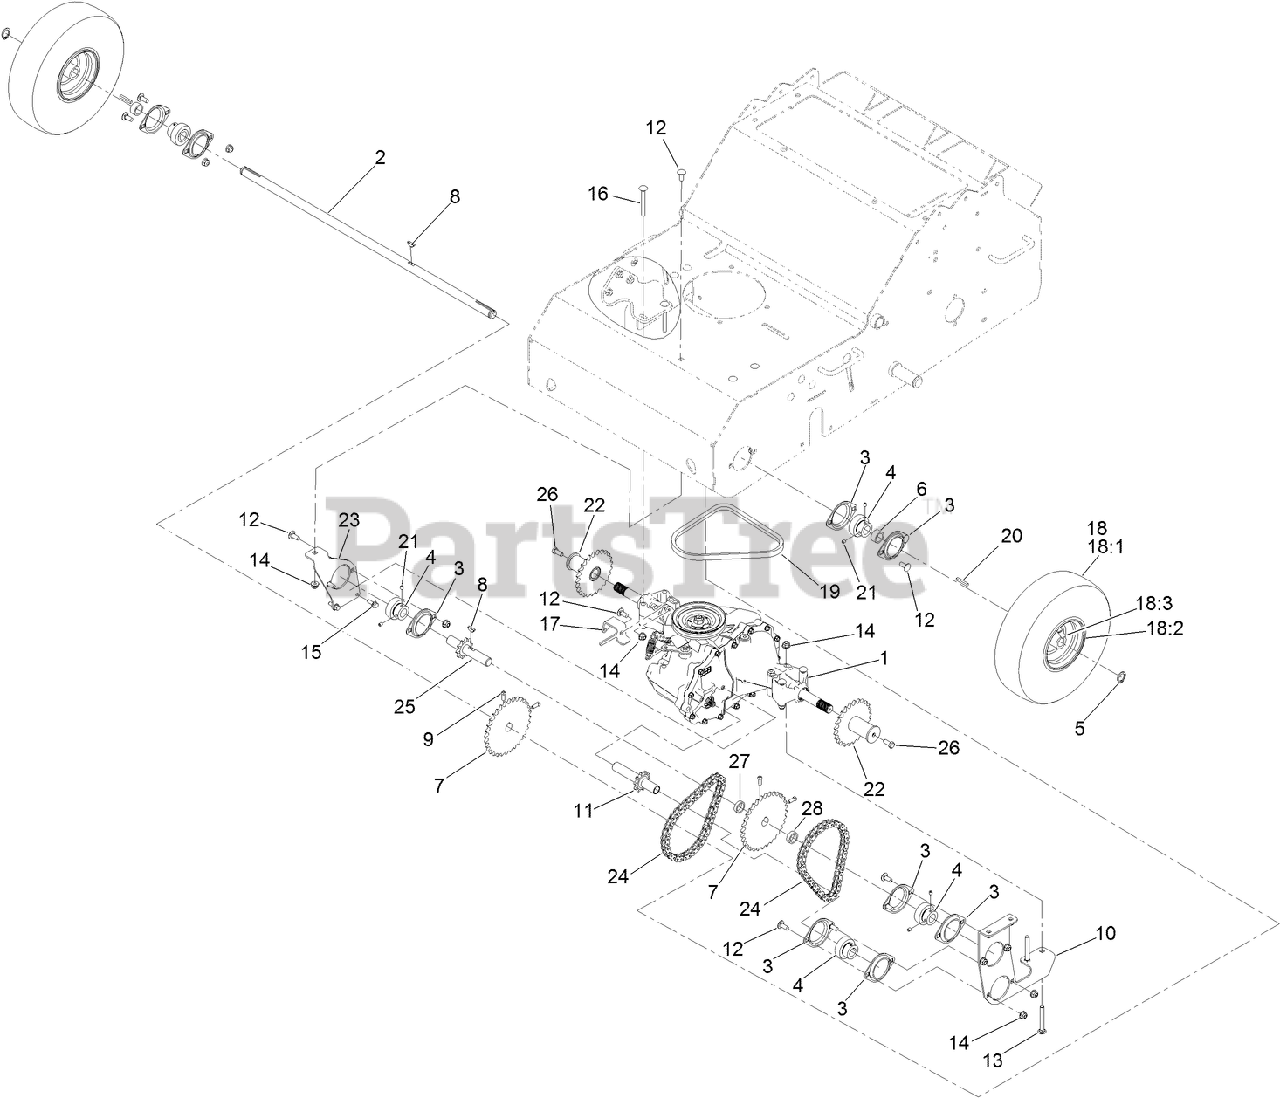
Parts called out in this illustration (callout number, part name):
1	TRANSAXLE ASM
2	SHAFT-WHEEL
3	FLANGE-BEARING
4	BEARING-LOCK, COLLAR
5	RING-RETAINING
6	SPACER-WHEEL
7	SPROCKET
8	KEY-WOODRUFF
9	SCREW-SET
10	PLATE-BEARING
11	SHAFT-OUTPUT
12	SCREW-CARR
13	SCREW-CARR
14	NUT-HF, NI
15	SCREW-HHF
16	SCREW-CARR
17	ANGLE-CONTROL
18	WHEEL AND TIRE ASM
18:2	RIM-GRAY
18:3	VALVE
19	BELT-DRIVE
20	KEY-SQUARE
21	SCREW-SET, HSH
22	SPROCKET
23	BRACKET-SUPPORT, SHAFT
24	CHAIN-DRIVE WHEEL
25	SHAFT-JACK
26	SCREW-HH
27	SPACER
28	SPACER-CONTROL
